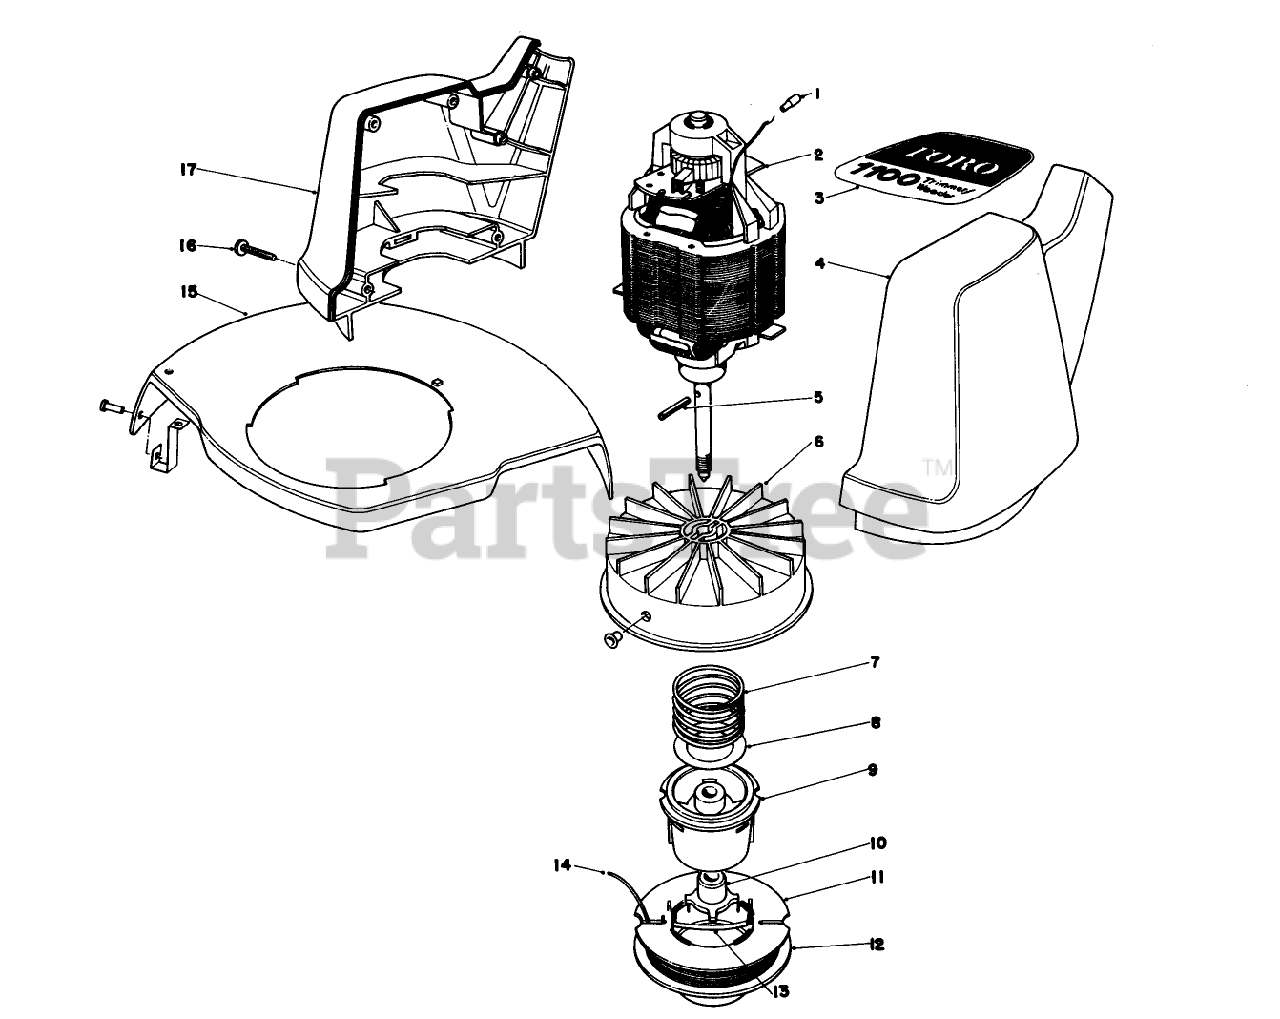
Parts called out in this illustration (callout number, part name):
1	CONNECTOR WIRE JOINT
2	Motor
3	Toro 1100 Decal
4	Left Motor Housing
5	COIL PIN
6	DRUM W/EYELET
7	SPRING COMPRESSION
8	WASHER-FLAT
9	SPOOL CORE
10	Driver
11	Empty SPooI
12	Cutting Line (50 .065" Dia.)
13	SADDLE-SPOOL CAP
14	LINE-FILIMENT
15	Shield with Cut Off Blade
16	SCREW-PPH
17	Right Motor Housing
